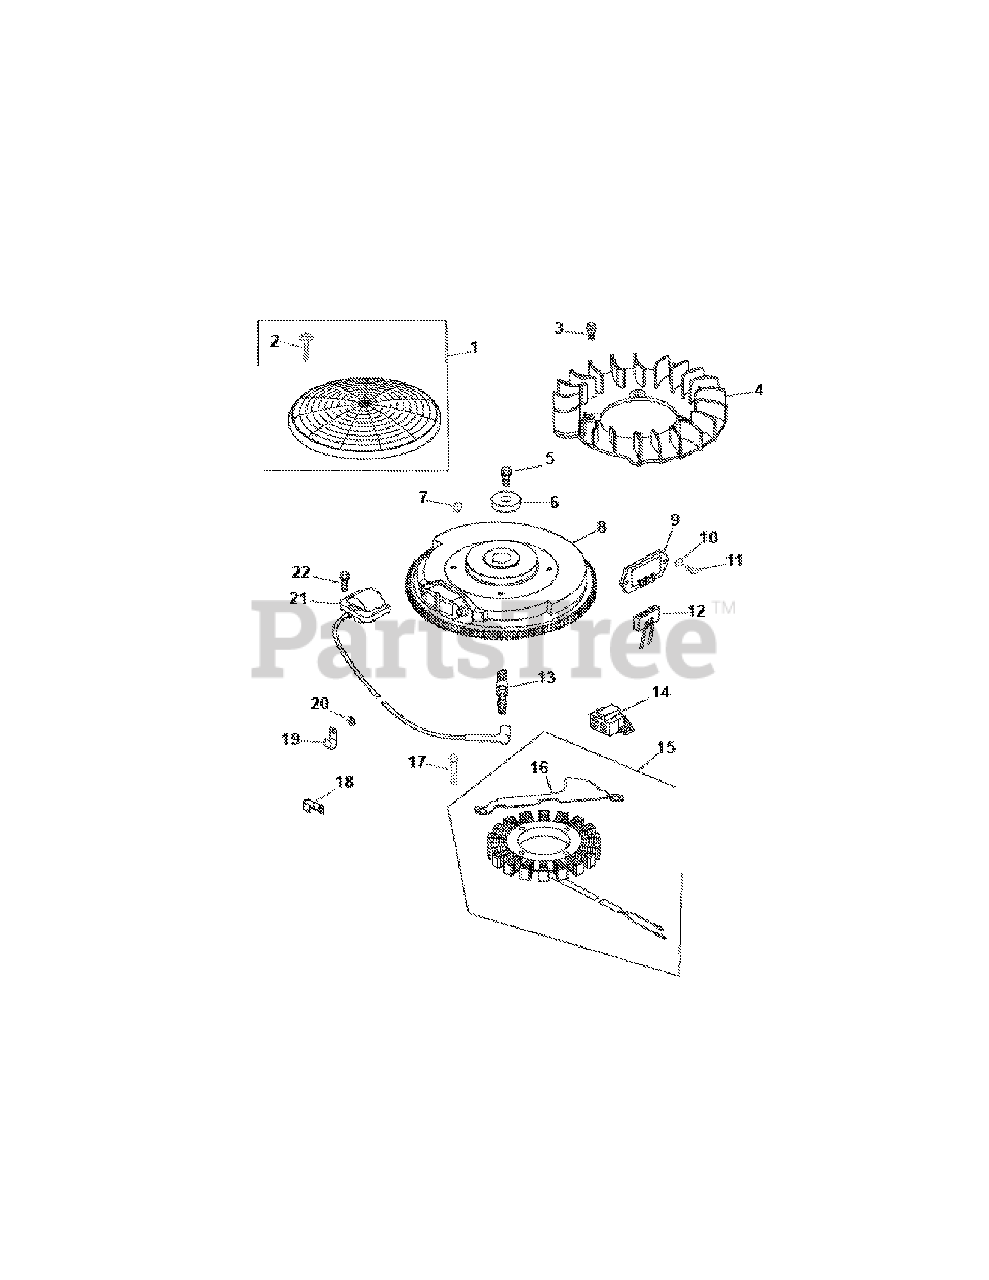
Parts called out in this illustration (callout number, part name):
1	Grass Screen Kit
3	Shoulder Bolt
4	Fan
5	Hex Flange Screw
8	Flywheel
9	Regulator Rectifier
11	Hex Head Screw
12	Connector
13	Spark Plug
15	15 amp Stator
16	Stator Wire Bracket
17	Hex Head Screw
18	Cable Clip
21	Ignition Module
22	Screw
